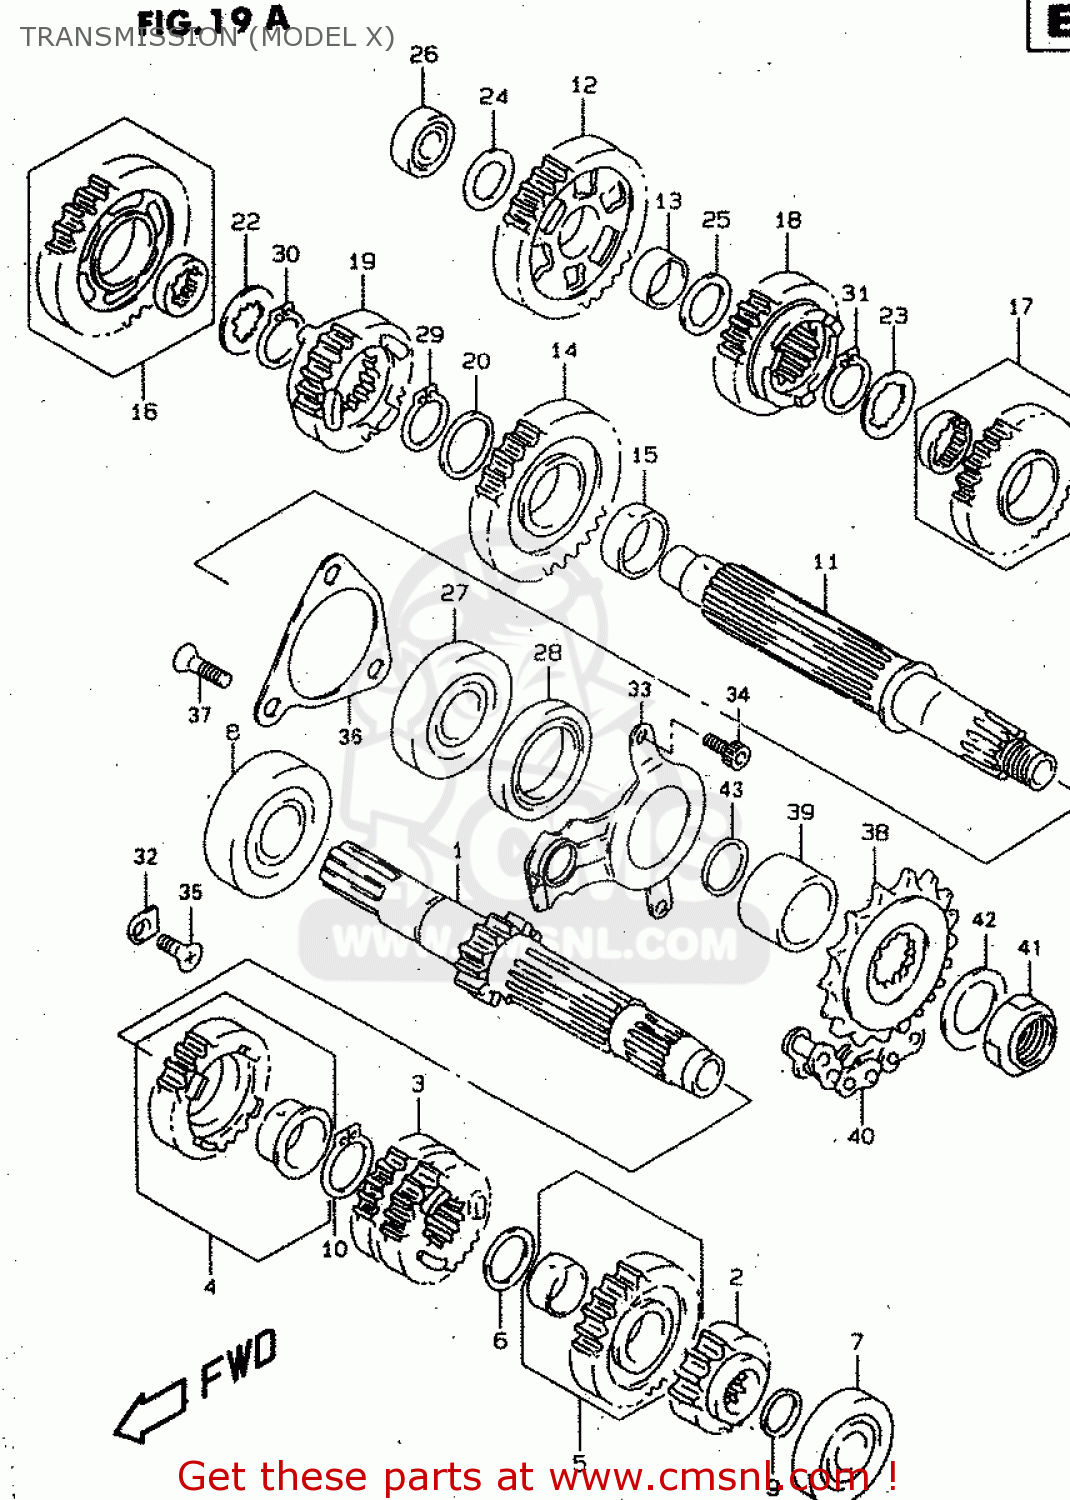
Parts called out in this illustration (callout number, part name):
1	SHAFT,COUNTER(NT:12)
2	GEAR,2ND DRIVE(NT:15)
3	GEAR,3RD & 4TH DRIVE(NT:18/27)
4	GEAR SET,FIFTH DRIVE (NT:
5	GEAR SET,SIXTH DRIVE (NT:
6	SHIM(22X30X1)
7	BEARING(20X47X14)
8	BEARING(25X62X17)
9	O RING(D:1.9,ID:16.6)
10	CIRCLIP
11	SHAFT,DRIVE
12	GEAR,1ST DRIVEN(NT:32)
13	BUSH
14	GEAR,2ND DRIVEN(NT:29)
15	BUSH,2ND DRIVEN GEAR
16	GEAR SET,THIRD DRIVEN (NT
17	GEAR SET,FOURTH DRIVEN (NT
18	GEAR,5TH DRIVEN(NT:25)
19	GEAR,SIXTH DRIVEN (NT:24)
20	WASHER(27X36X1)
21	WASHER,LOCK
22	WASHER,3RD & 4TH DRIVEN
23	WASHER,3RD & 4TH DRIVEN
24	SHIM(20X34X1)
25	SHIM(22X34X1)
26	BEARING(20X52X15)
27	BEARING(28X68X20)
28	SEAL,OIL(38X52X8)
29	CIRCLIP
30	CIRCLIP
31	CIRCLIP
32	RETAINER
33	RETAINER,DRIVESHAFT O
34	BOLT,STRANGER
35	SCREW
36	RETAINER,DRIVE SHAFT BEARING
37	SCREW(6X12)
38	SPROCKET,ENGINE (NT:17)
39	SPACER,ENGINE SPROCKET
40	CHAIN ASSEMBLY RK50GSVZ1.1
41	NUT
42	SHIM(25X40X1.5)
43	O RING(D:2.4,ID:23.7)
